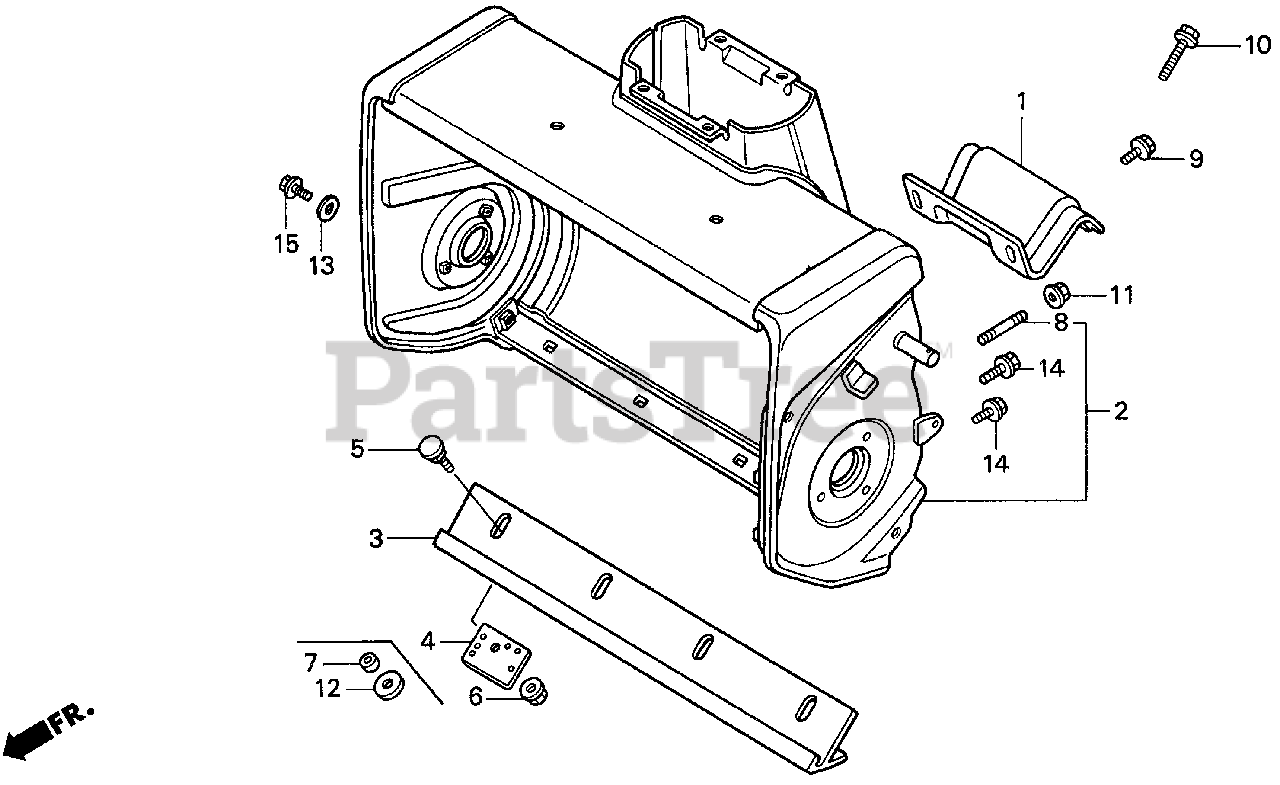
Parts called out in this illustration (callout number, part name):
1	STIFFENER, FRAME
2	HOUSING, AUGER *NH1* (BLACK)
3	BLADE, SCRAPER
4	PLATE, SCRAPER HOLDER
5	BOLT, PAN (6MM)
6	NUT, SELF-LOCK (6MM)
7	COLLAR, SCRAPER BLADE
8	BOLT 2, STUD (6X18)
9	BOLT-WASHER (6X16)
10	BOLT-WASHER (6X28)
11	NUT, FLANGE (6MM)
12	WASHER, PLAIN (6MM)
13	WASHER, PLAIN (6MM)
14	BOLT, FLANGE (6X12)
15	BOLT, FLANGE (6X12)
